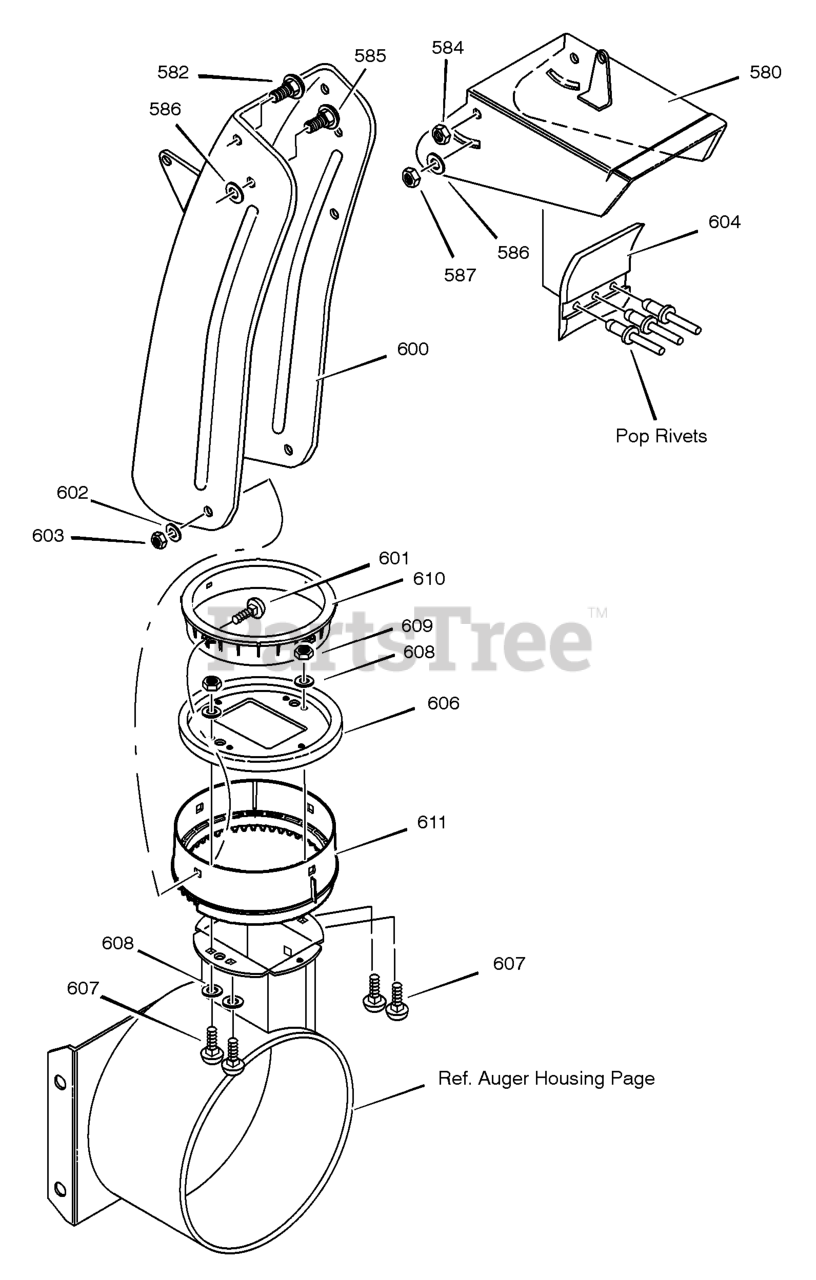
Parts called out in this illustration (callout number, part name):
580	CHUTE, UPPER W/REMOTE
582	SCREW, 5/16-18 x 0.75
584	NUT
585	SCREW, 5/16-18 x 0.75
586	PLASTIC WASHER
587	NUT
600	CHUTE, LOWER W/REMOTE
602	WASHER, FLAT
603	NUT
606	CHUTE COLLAR
607	BOLT
608	WASHER, FLAT
610	RETAINER, RING INNER
611	RETAINER, RING OUTER
